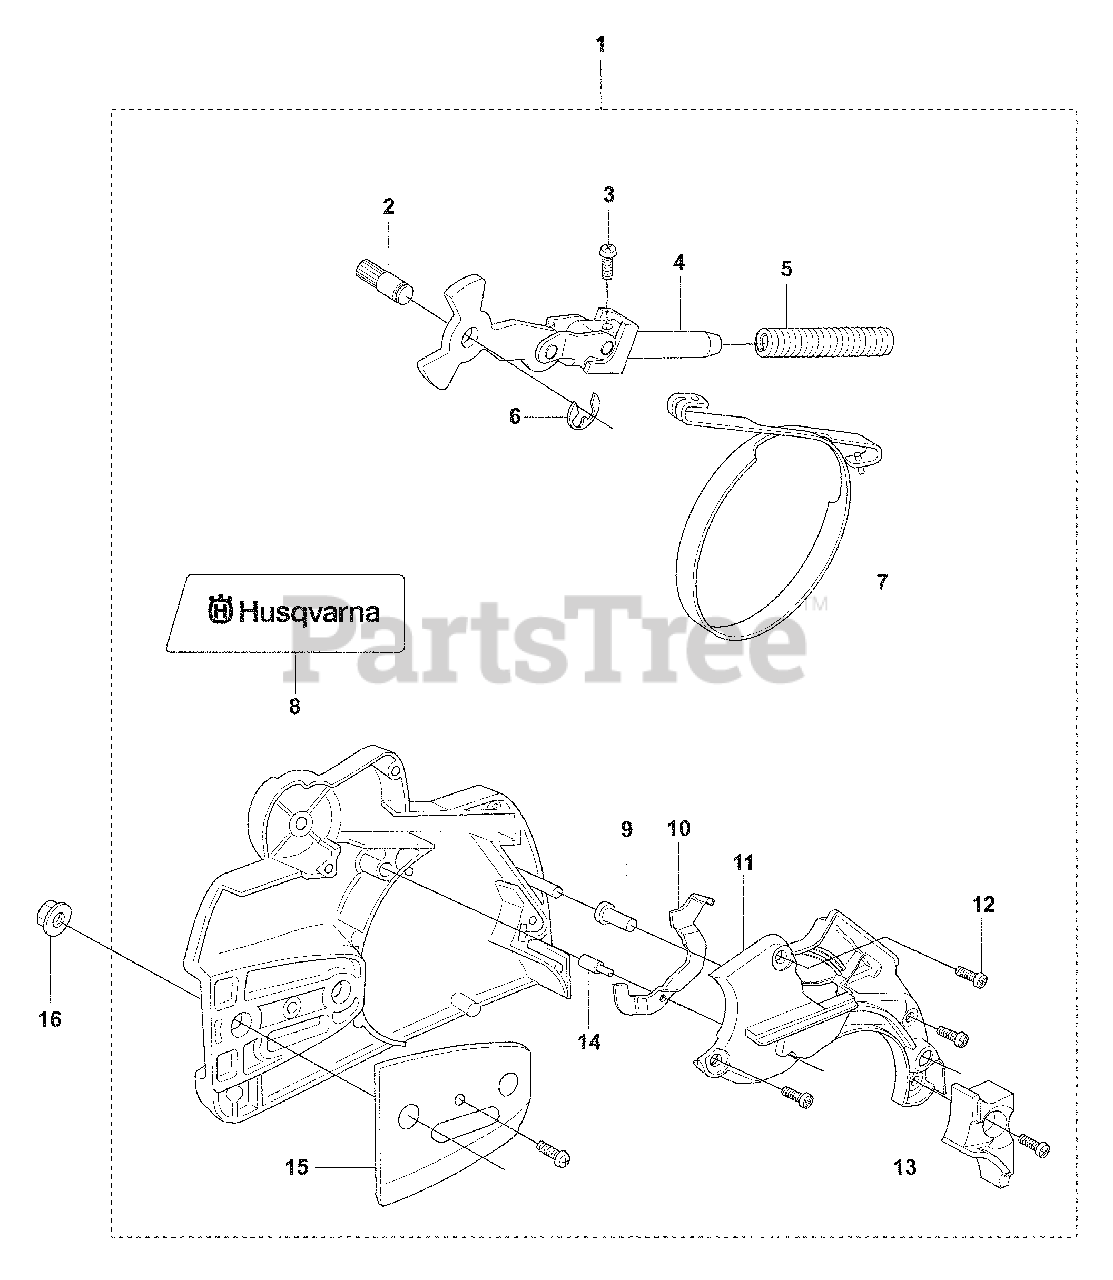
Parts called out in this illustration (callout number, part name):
1	CHAIN BRAKE
6	Bar Retainer
7	BRAKE BAND
16	Flange Hex Nut, M8
